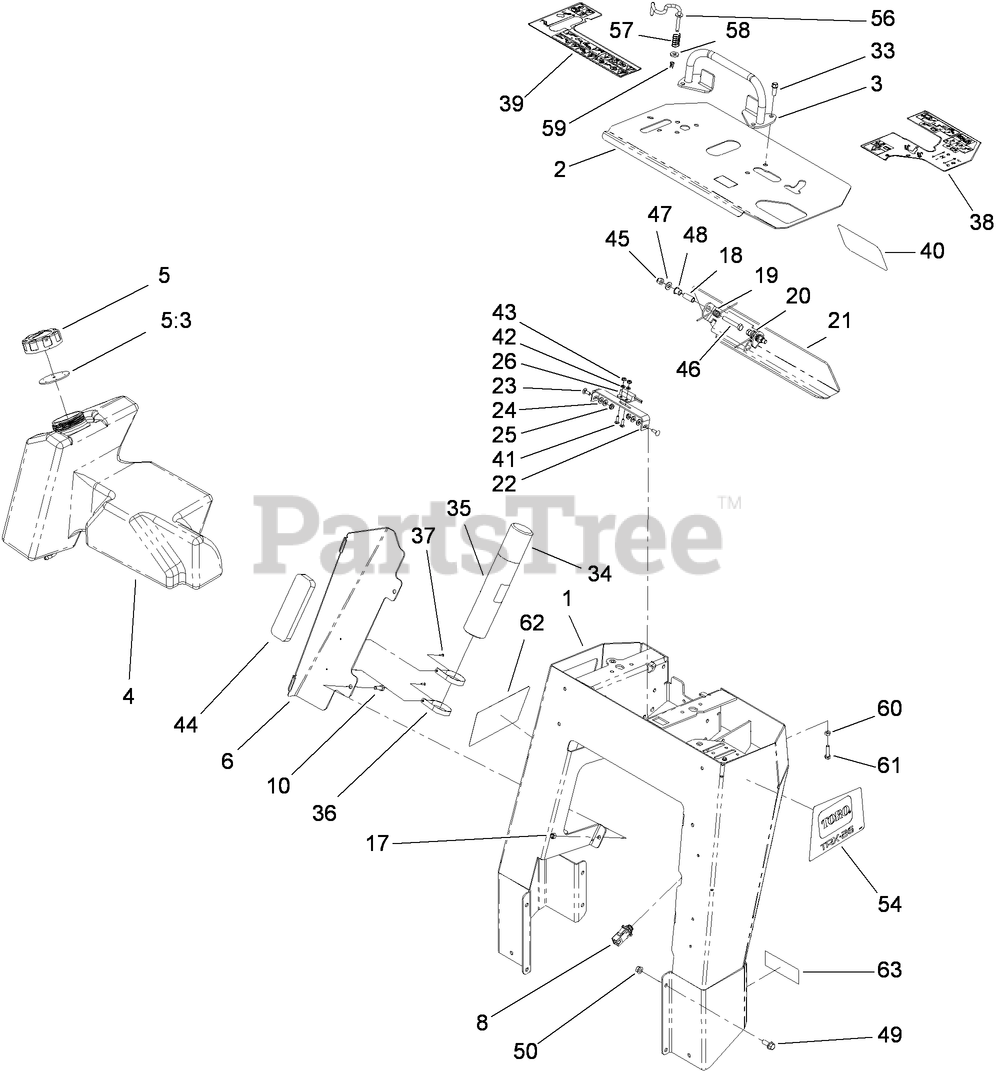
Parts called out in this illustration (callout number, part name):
2	PANEL-CONTROL
3	BAR-REFERENCE
4	TANK-FUEL
5	CAP-FUEL, GAS
5:3	GASKET-VENTED
6	BRACKET-COVER, TANK
8	SWITCH-PLUNGER
10	SCREW-HH
17	NUT-LOCK, NI
18	SPACER-SPRING
19	SPRING-TORSION, LH
20	SPRING-TORSION, RH
21	PLATE-REVERSE
22	PLATE-SWITCH
23	BOLT-CARR
24	WASHER-FLAT
25	NUT-KEPS
26	SWITCH-PROXIMITY
33	SCREW-TAPTITE
34	CAP-HOUSING
35	TUBE-MANUAL
36	CLAMP-R
37	RIVET-POP
38	DECAL-CONSOLE, LH
39	DECAL-CONSOLE, RH
41	SCREW-CARR
42	WASHER-FLAT
43	NUT-KEPS
44	PAD-FOAM
45	NUT-LOCK, NI
46	SCREW-HH
47	WASHER-FLAT
48	BUSHING-NYLINER
49	SCREW-HHF
50	NUT-FLANGE
54	DECAL-SIDE, LH
56	ROD-INTERLOCK
57	SPRING-CONTROL
58	WASHER-FLAT
59	PIN-COTTER
60	SCREW-HH
61	NUT-JAM
62	DECAL-SIDE, RH
63	DECAL-ARRESTER, SPARK
